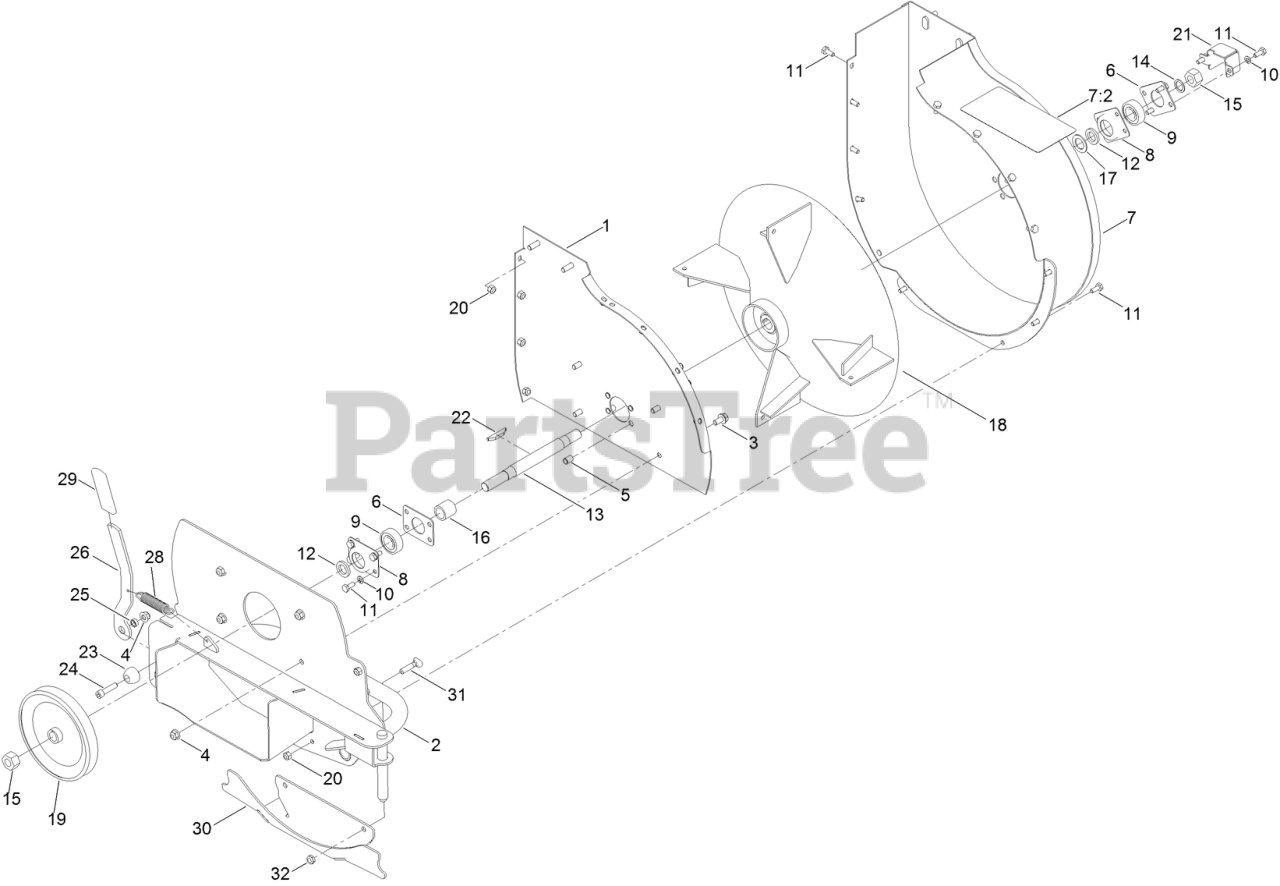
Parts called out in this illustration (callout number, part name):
1	MOUNTING PLATE ASM
2	BLOWER PIVOT ASM
3	SCREW-HHF
4	NUT-HF, NI
5	NUT-CLINCH
6	PLATE-COVER
7	BLOWER HOUSING OUTER ASM
7:2	DECAL-WARNING, BLOWER
8	CUP-BEARING
9	BEARING-BALL
10	WASHER-LOCK
11	SCREW-HH
12	SPACER-BEARING
13	SHAFT-BLOWER
14	WASHER-FLAT
15	NUT-HEX
17	WASHER-THRUST
18	IMPELLER ASM
19	PULLEY-TRANSAXLE
20	NUT-LOCK, NI
21	COVER-SHAFT
23	PIN-GUIDE
24	SCREW-HSH
25	SPACER-ARM, IDLER
26	HANDLE
28	SPRING-RETURN, PEDAL
30	PLATE-SKID
31	SCREW-HANDLE
32	NUT-LOCK, NI
